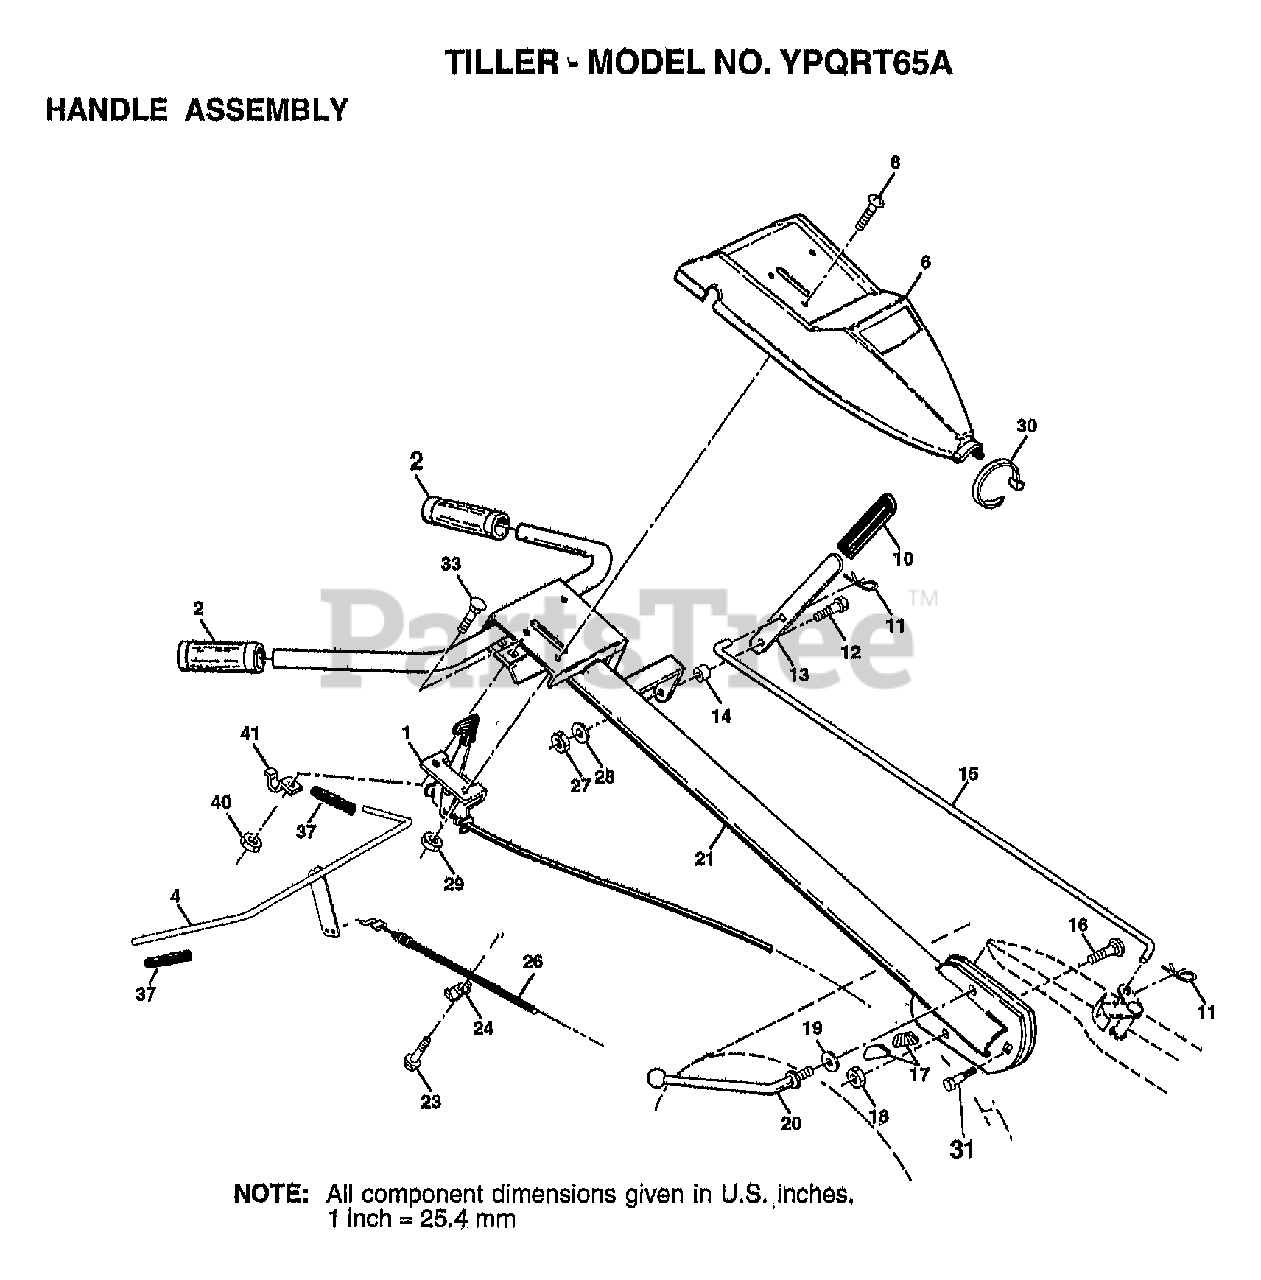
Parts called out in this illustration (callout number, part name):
1	CONTROL.THROTTLE
4	BAR ASM CONTROL
6	"PANEL,CONT TI"
8	SCREW.PNHD.10-24
10	GRIP T
11	RETAINER M
12	SHOULDER BOLT ST
13	SHIFT HANDLE CRT
14	GROMMET CRT
15	SHIFT ROD CRT
16	BOLT D
17	LOCK CRT
18	LOCKNUT
19	WASHER CRT
20	LEVER LOCK CRT
24	CONDIUT CLIP T
26	CABLE.CLUTCH
28	LOCKWASHER
30	TIE CABLE CRT
31	BOLT PIVOT
33	BOLT
37	GRIP BAR CRT
40	NUT
